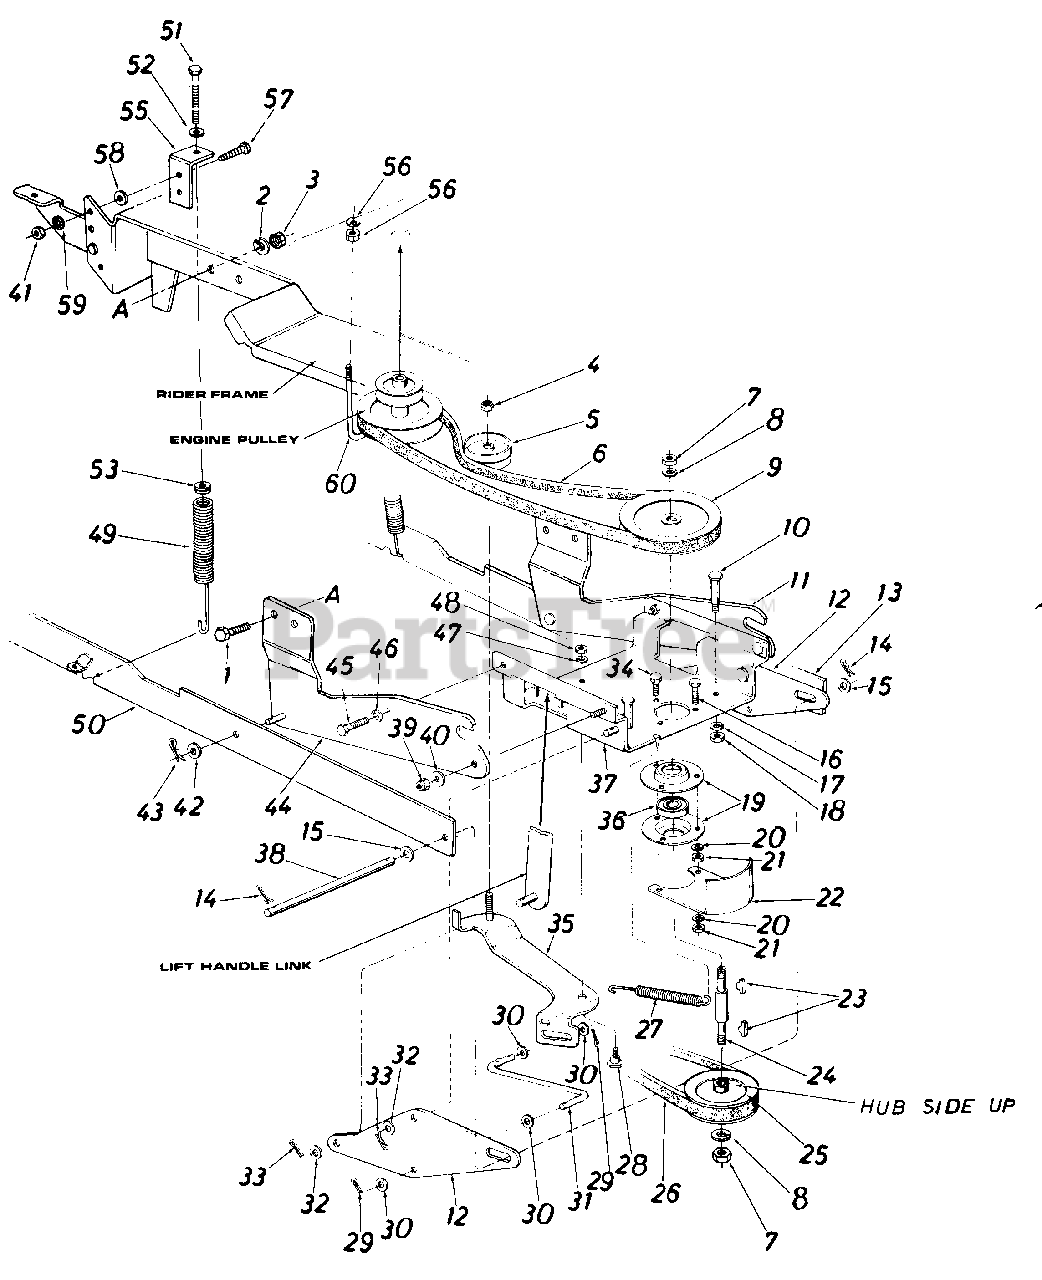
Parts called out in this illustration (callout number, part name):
1	HexScr. 1/4-28x.75" Lg. Grade 5
2	L-Wash. 1/4" Scr.
3	Hex Nut 1/4-28 Thd.
4	Hex Ins. Jam Nut 3/8-24 Thd.
5	Flat Idler 3.25" O.D.
6	"V"-Belt 1/2 x 49" Lg.
7	Hex Jam Nut 5/8-11 Thd.
8	L Wash. 5/8" I.D.
9	6.50" O.D. x 5/8 Pulley
10	ShoulderScrew
11	Channel Supporting Brkt.-R.H.
12	Linkage Brkt.
13	Linkage Arm Ass'y. R.H.
14	Intern. Cotter Pin .500" Dia.
15	Fl.-Wash.
16	HexScr. 5/16-18x 1.25" Lg.
17	L.-Wash. 3/8" Scr.
18	Hex Nut 3/8-16 Thd.
19	Bearing Housing
20	L.-Wash. 5/16" Scr.
21	Hex Nut 5/16-18 Thd.
24	Pulley Spindle
25	4.00 O.D. x 5/8 Pulley
26	"V"-Belt 1/2 x 85.2" Lg.
27	Extension Spring
28	Shoulder Screw
29	Cotter Pin 3/32" Dia. x 1 .00
30	Fl-Wash.
31	Control Rod
32	Fl-Wash.
33	Inter. Cotter Pin .500" Dia.
34	Hex Sems Scr. 5/16-18 x .75" Lg.
35	Clutch Idler Brkt. Ass'y.
36	Ball Bearing
37	Channel Ass'y.
38	Lift Handle Shaft
39	Hex Ins. L-Nut3/8-16 Thd.
40	Fl.-Wash.
41	Hex Nut 1/4-20 Thd.
42	F l.-Wash.
43	Intern. Cotter Pin .500" Dia.
44	Channel Supporting Brkt.-L.H.
45	Hex Scr. 3/8-16 x 1.00" Lg.
46	L.-Wash. 3/8" Scr.
47	L.-Wash. 5/16" Scr.
48	Hex Nut 5/16-18 Thd.
49	Helper Spring
50	Linkage Arm Ass'y.-L.H.
51	HexScr.5/16-18x 2.0" Lg Special
52	Fl.-Wash. 5/16" Scr.
53	Spring Insert
57	Hex Bolt 1/4-20 x .75" Lg.
58	Fl.-Wash..264" I.D.
59	L.-Wash. 1/4" I.D.
60	J-Bolt 5/16-18
